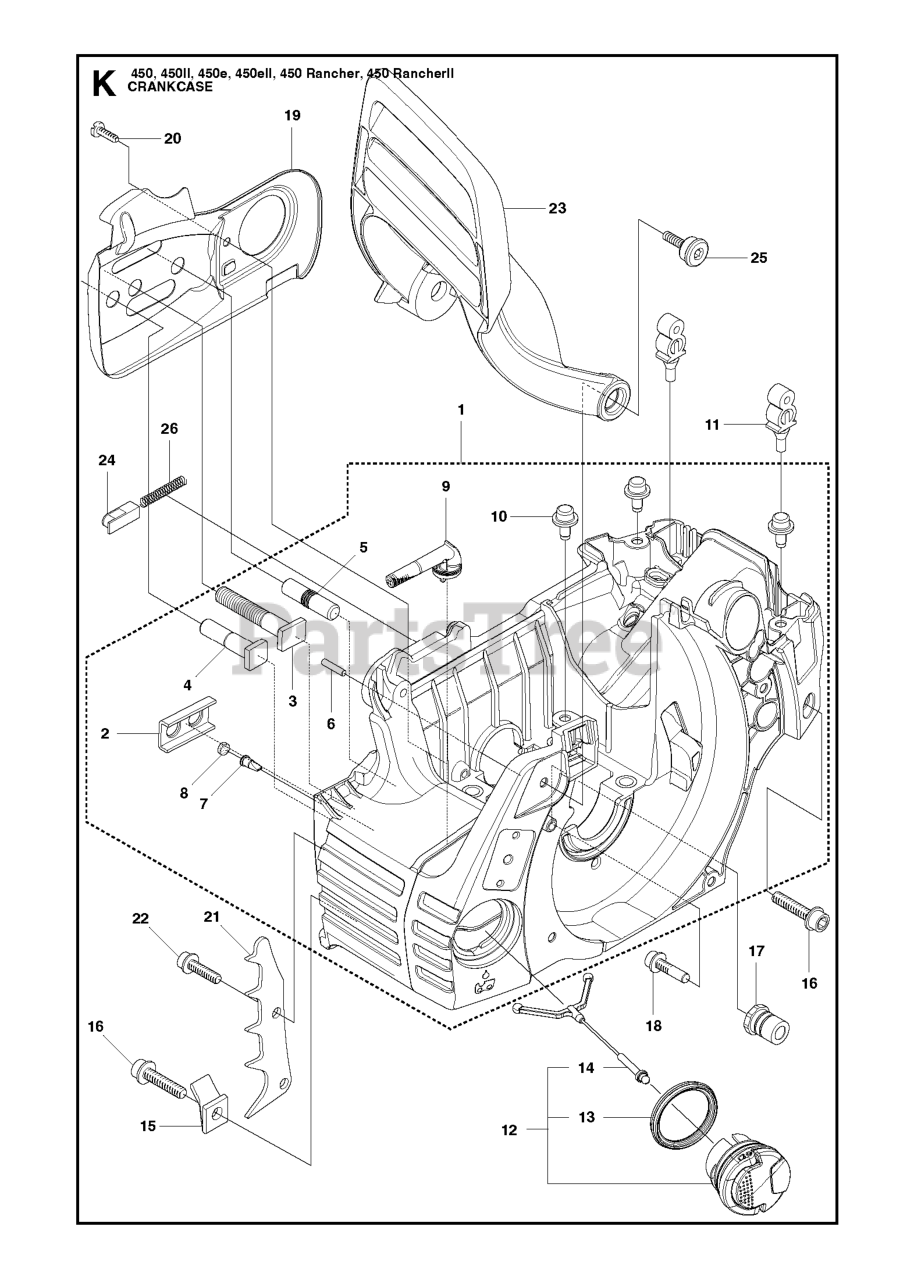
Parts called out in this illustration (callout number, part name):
1	CRANKCASE
2	STIFFENING PLATE
7	VALVE-CHECK (DUCKBILL)
8	PLUG
9	OIL SCREEN
12	TANK CAP ASSY
15	CHAIN CATCHER
17	LATERAL SUPPORT
18	SCREW IHSCFT
19	CHAIN GUIDE PLATE
23	HAND GUARD
26	LOCK SPRING
